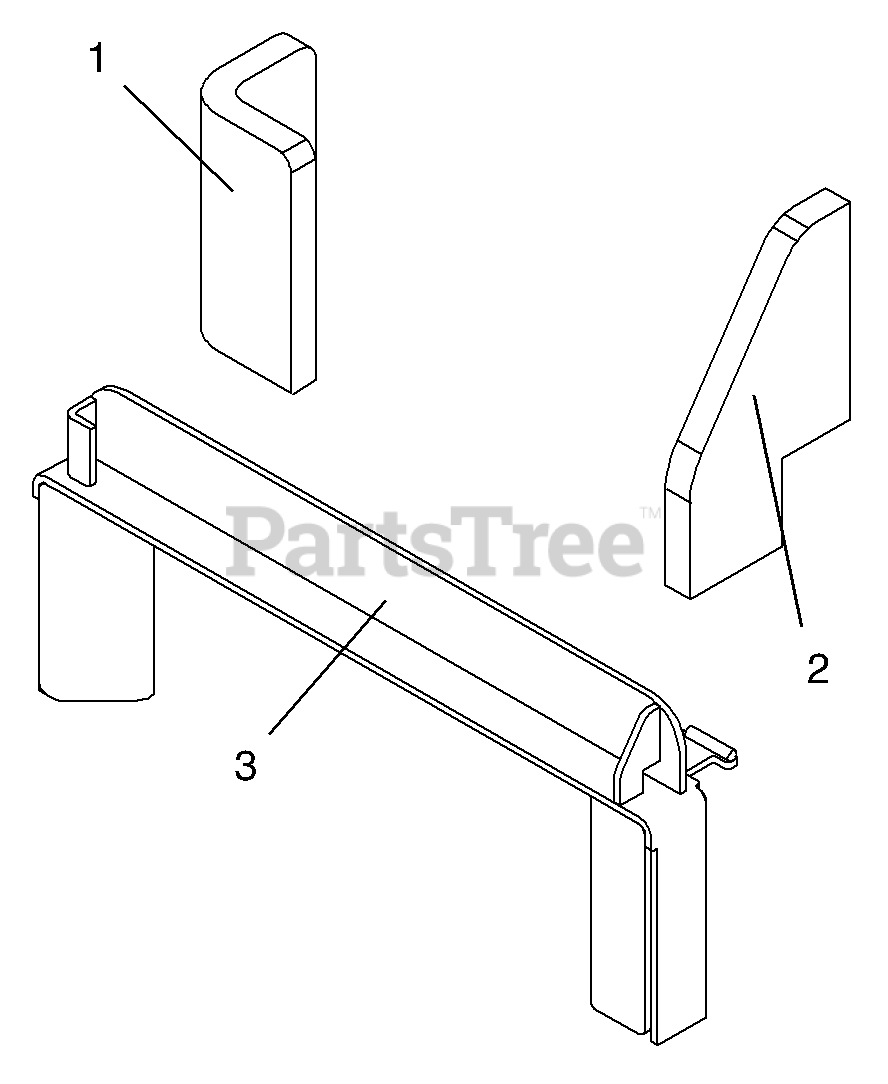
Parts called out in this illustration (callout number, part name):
1	Bagger Mount Bracket
2	Upper Bagger Mount Bracket
3	Bagger Extension Bracket
